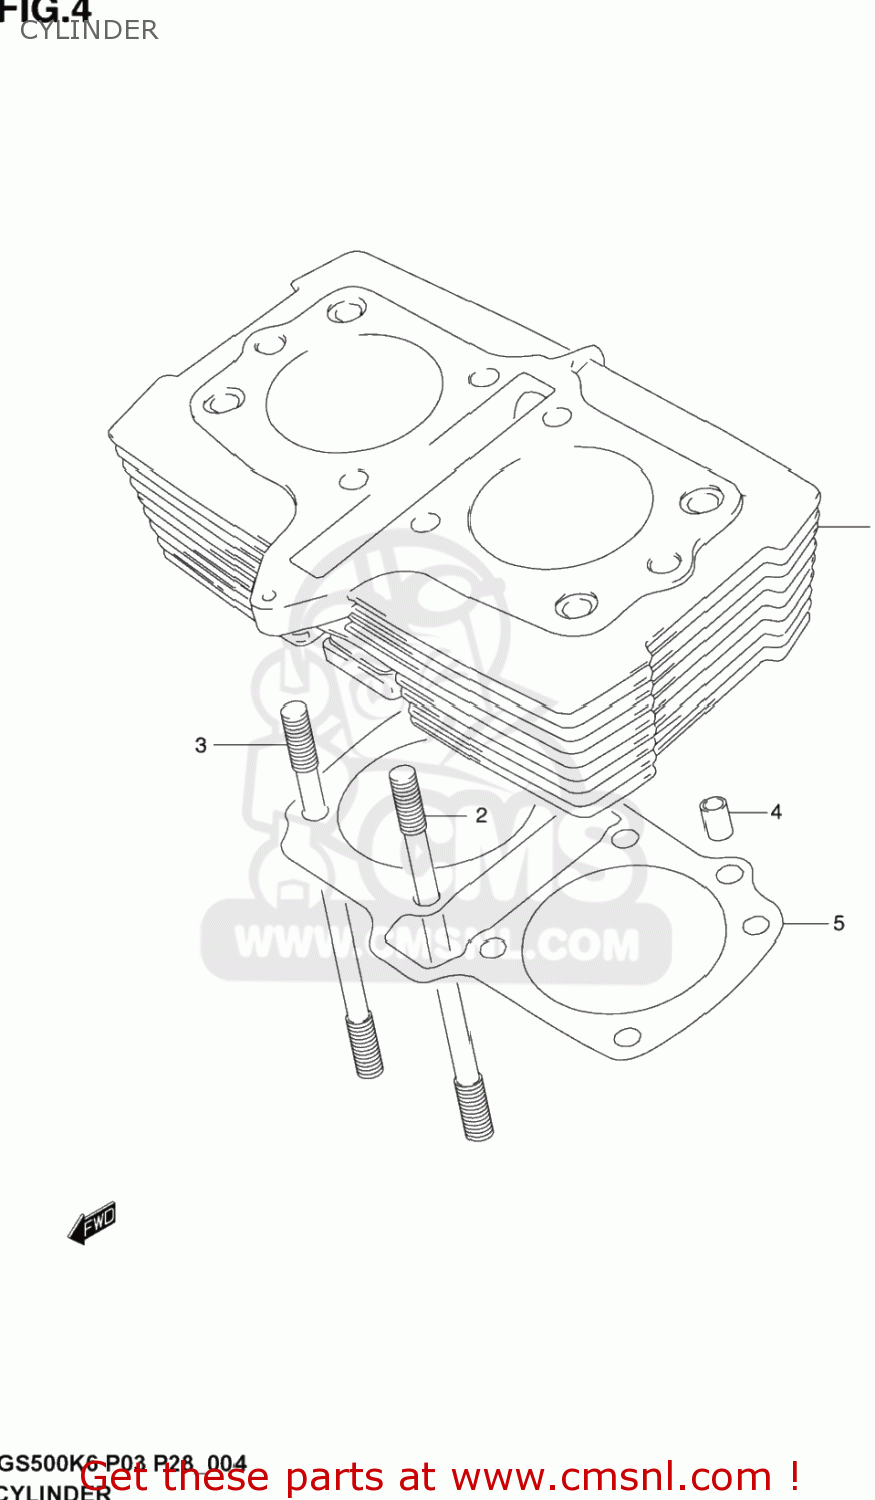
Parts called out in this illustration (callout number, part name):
1	CYLINDER
2	BOLT,STUD
3	BOLT,STUD
4	PIN
5	GASKET,CYLINDER (NAS)
